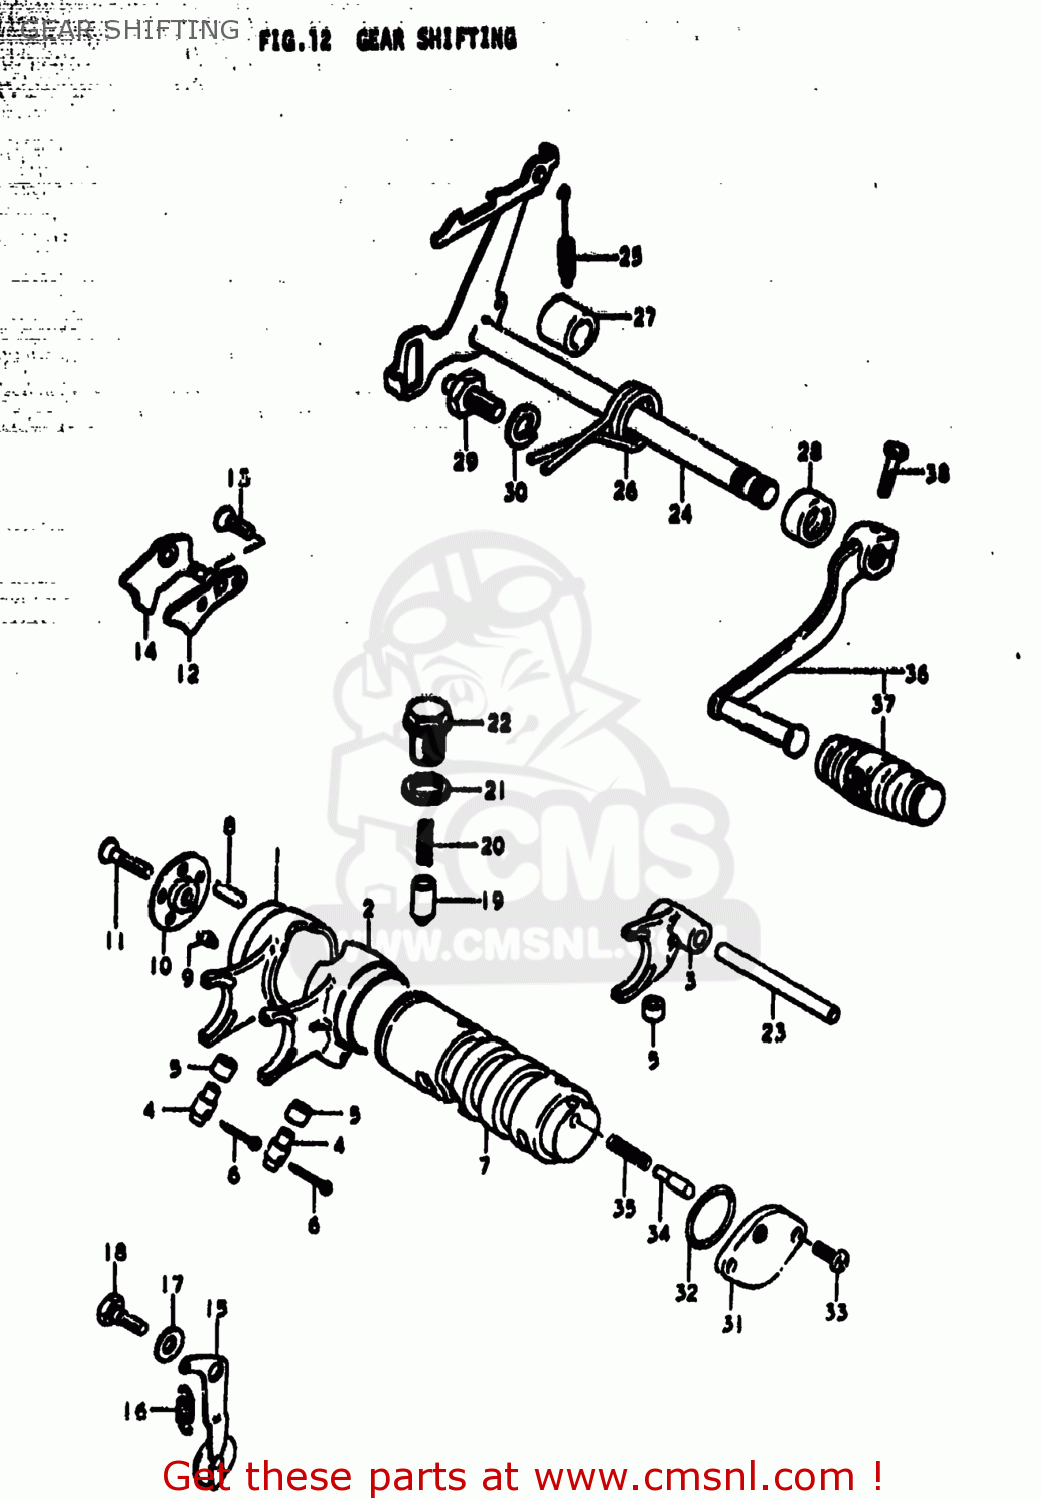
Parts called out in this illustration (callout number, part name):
1	FORK,GEAR SHIFT NO.1
2	FORK,GEAR SHIFT NO.2
3	FORK,GEAR SHIFT NO.3
4	PIN
5	SPACER
6	PIN 25X20
7	CAM,GEAR SHIFT
8	ROLLER(4X13.8)
9	PIN
10	RETAINER,GEAR SHIFT CAM DR PIN
11	SCREW
12	GUIDE,GEAR SHIFT CAM
13	SCREW
14	PAWL,GEAR SHIFT CAM STOPPER
15	STOPPER,GEAR SHIFT CAM
16	SPRING
17	WASHER(6.5X16X2.3)
18	BOLT(6X16.1)
19	STOPPER,GEAR SHIFTING
20	SPRING
21	GASKET(14X19.2X2) (NAS)
22	BOLT,GEAR SHAFT CAM STOPPER
23	SHAFT,GEAR SHIFT FORK
24	SHAFT,GEAR SHIFT
25	SPRING
26	SPRING
27	SPACER(12X20X15.3)
28	OIL SEAL
29	STOPPER,GEAR SHIFT ARM
30	WASHER
31	BODY,GEAR SHIFT SWITCH
32	O-RING (D:2.4 ID:26.2)
33	SCREW
34	PIN(5X15.5)
35	SPRING
36	LEVER ASSY,GEAR SHIFT
37	RUBBER,GEAR SHIFT PEDAL
38	BOLT
